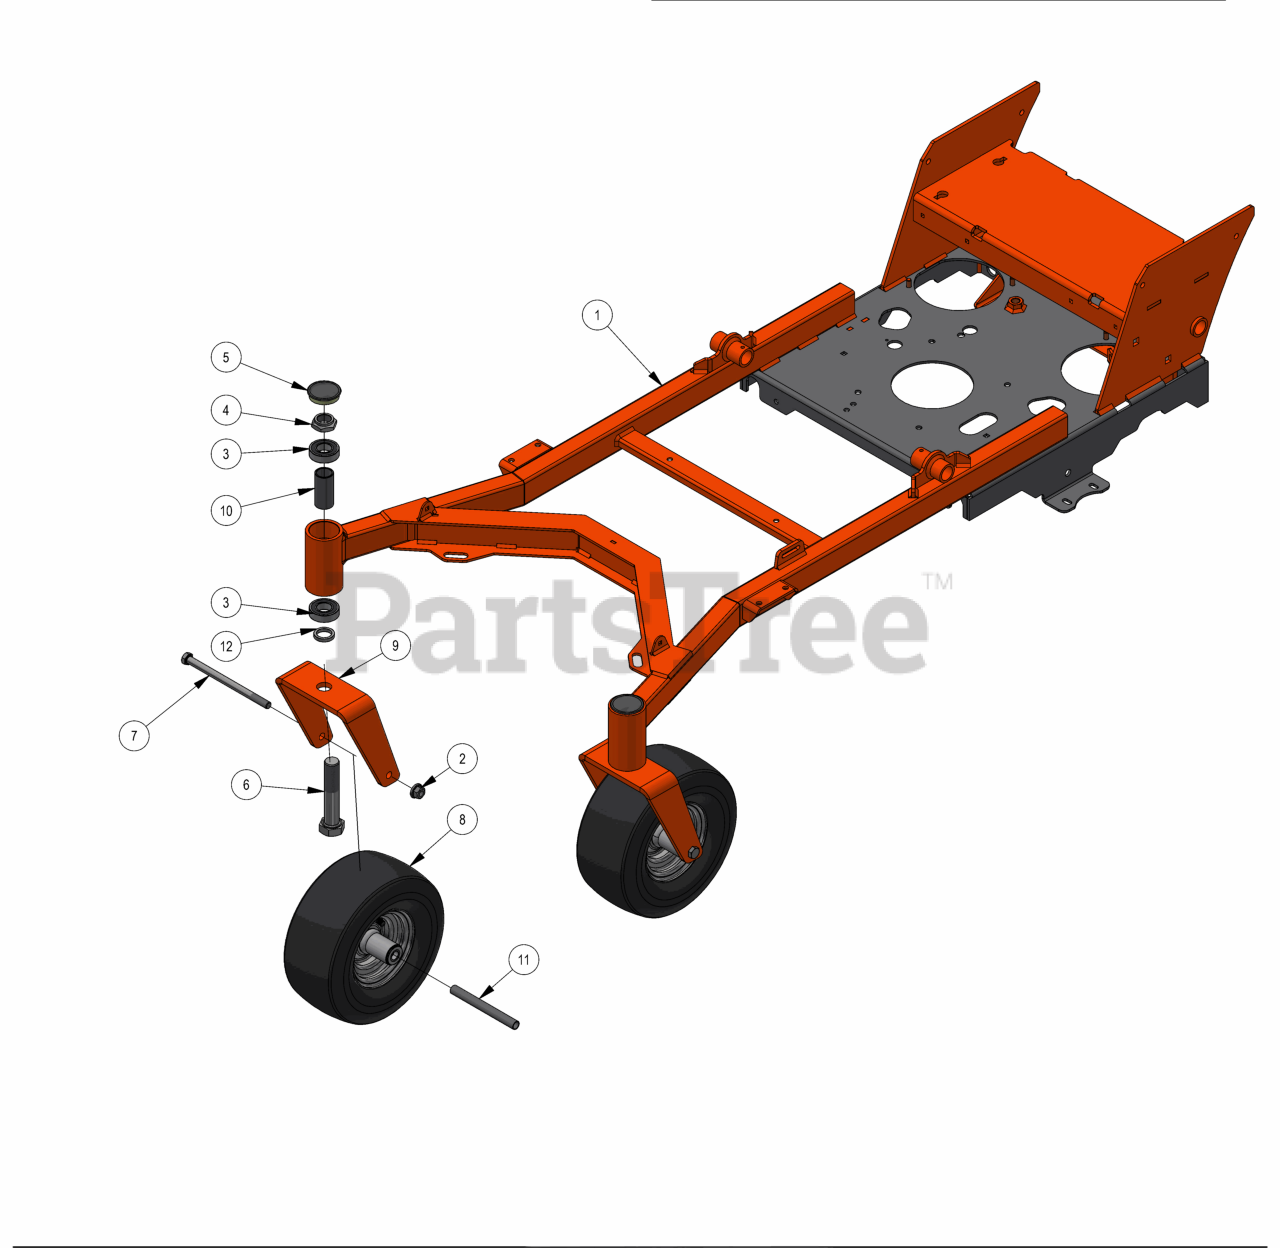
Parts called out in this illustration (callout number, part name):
1	2023 Walk Frame
2	1/2-13 NYLON INSERT FLANGE LOCKNUT ZINC
3	1641 BEARING W/2 CONTACT RUBBER SEALS
4	1"-14 NYLON INSERT JAM LOCKNUT ZINC
5	2017 Bearing Cover
6	1"-14 X 5 HEX CAP SCREW (GR.8) ZINC YELLOW
7	1/2-13 X 7-1/2 HEX CAP SCREW (GR.5) ZINC
8	11x6.00-5 Front Assembly - Black Wheel
9	2017 MZ Front fork
10	2016 Front Bearing Spacer
11	Front Wheel Spanner
12	1.02 ID X 1.38 OD X .250 THK SPACER ZINC
